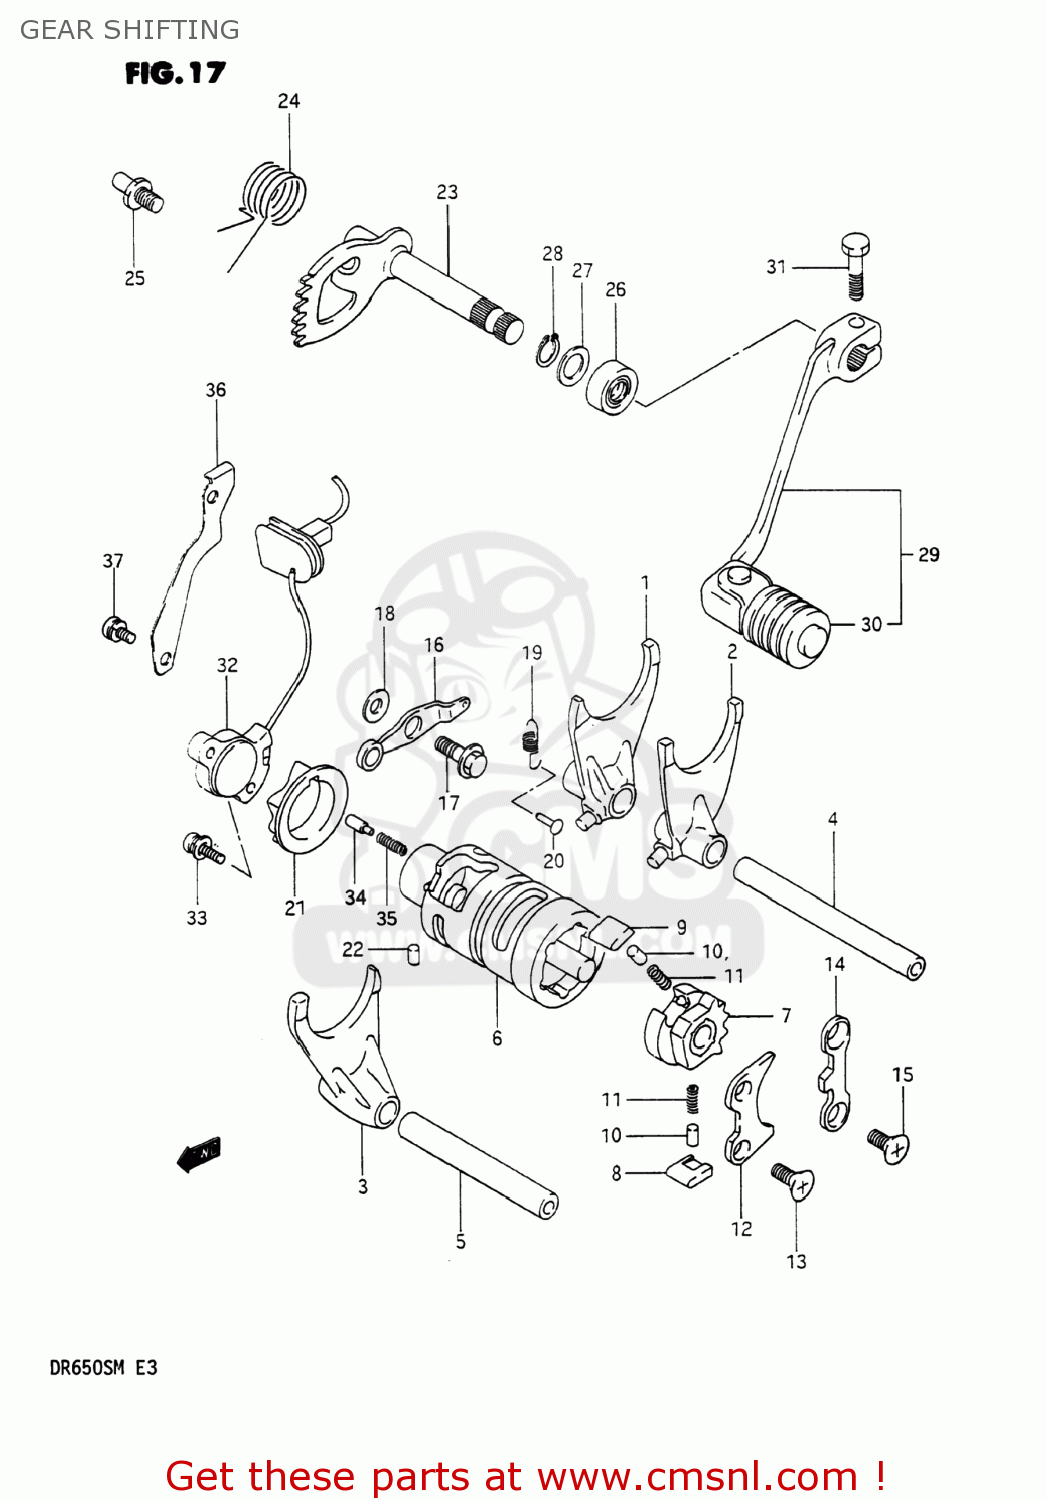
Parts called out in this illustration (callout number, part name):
1	FORK,GEAR SHIFT NO.1
2	FORK,GEAR SHIFT NO.2
3	FORK,GEAR SHIFT NO.3
4	SHAFT,GEAR SHIFT FORK
5	SHAFT,GEAR SHIFT FORK
6	CAM,GEAR SHIFT
7	GEAR,GEARSHIFT CAM DRIVE
8	PAWL,GEAR SHIFT NO.1
9	PAWL,GEAR SHIFT NO.2
10	PIN(5X8)
11	SPRING
12	LIFTER,GEAR SHAFT PAWL
13	SCREW
14	STOPPER,GEAR SHIFT POLE
15	SCREW
16	STOPPER,GEAR SHIFT CAM
17	BOLT
18	WASHER
19	SPRING
20	RIVET
21	PLATE,SHIFT CAM STOPPER
22	PIN 4X6
23	SHAFT,GEAR SHIFT
24	SPRING
25	STOPPER,GEAR SHIFT CAM
26	OIL SEAL
27	WASHER
28	CIRCLIP
29	LEVER ASSY,GEAR SHIFT
30	RUBBER,GEAR SHIFT PEDAL
31	BOLT
32	BASE ASSY,NEUTRAL SW TERMINAL
33	SCREW
34	PIN(5X15.5)
35	SPRING
36	CLAMP,LEAD WIRE
37	SCREW
